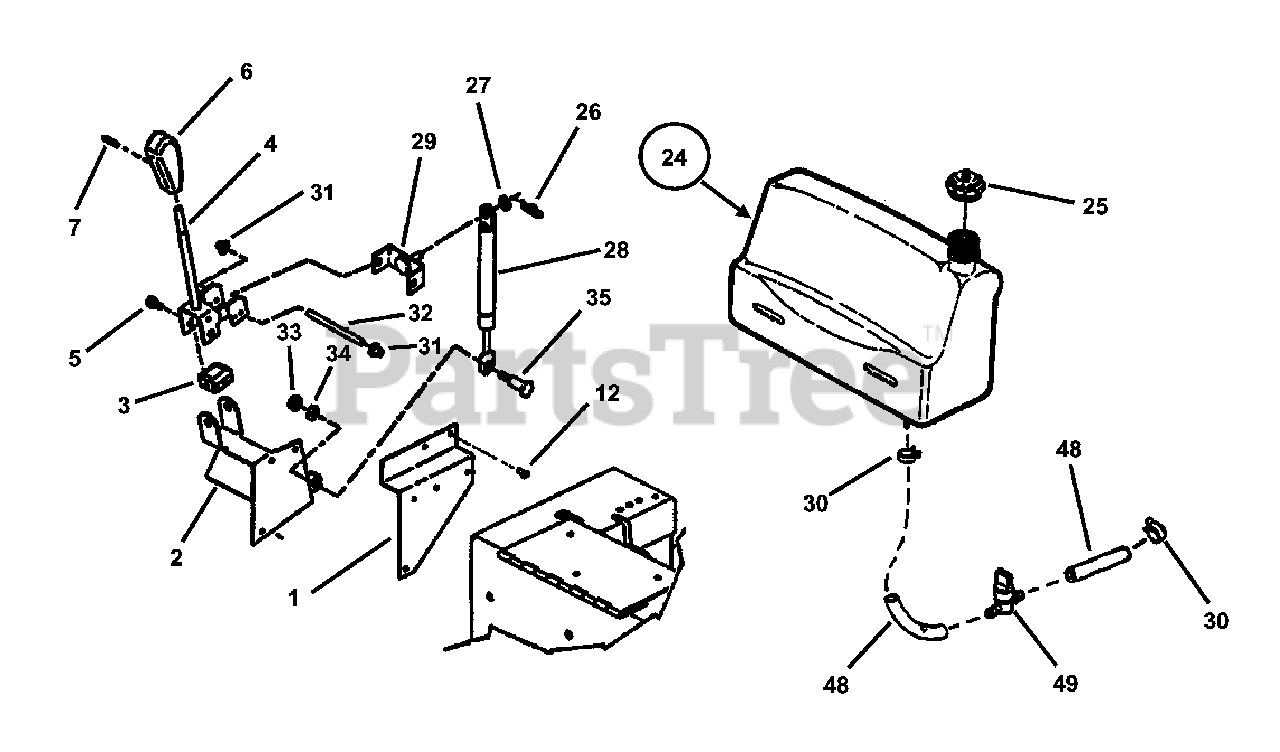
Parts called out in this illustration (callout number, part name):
1	BRACKET, R. Hand Tank Support
2	BRACKET, Joystick
3	PIVOT, Joystick Control
4	WELDMENT, Joystick Control Handle
5	BOLT, 5/16-18 x 3/4" Shoulder
6	LEVER, Shift Handle
7	PIN, 3/16 x 3/4" Roll
12	SCREW, 1/4 x 5/8" Pan Head Self-Tap
24	Ass'y, Fuel Tank
25	CAP, Fuel Tank (w/screw vent)
26	COTTER-PIN, 3/8 Self Locking
27	WASHER, 11/32 x 11/16" Flat
28	CYLINDER, Joystick Control
29	BRACKET, Joystick Control
30	CLAMP, Fuel Hose
31	PUSH-NUT, 1/4"
32	PIN, Joystick
33	NUT, 5/16-18 Hex, Grade 5
35	BOLT, 5/16-18 Shoulder
48	LINE, Fuel, 5"
49	SHUT-OFF VALVE, Fuel
